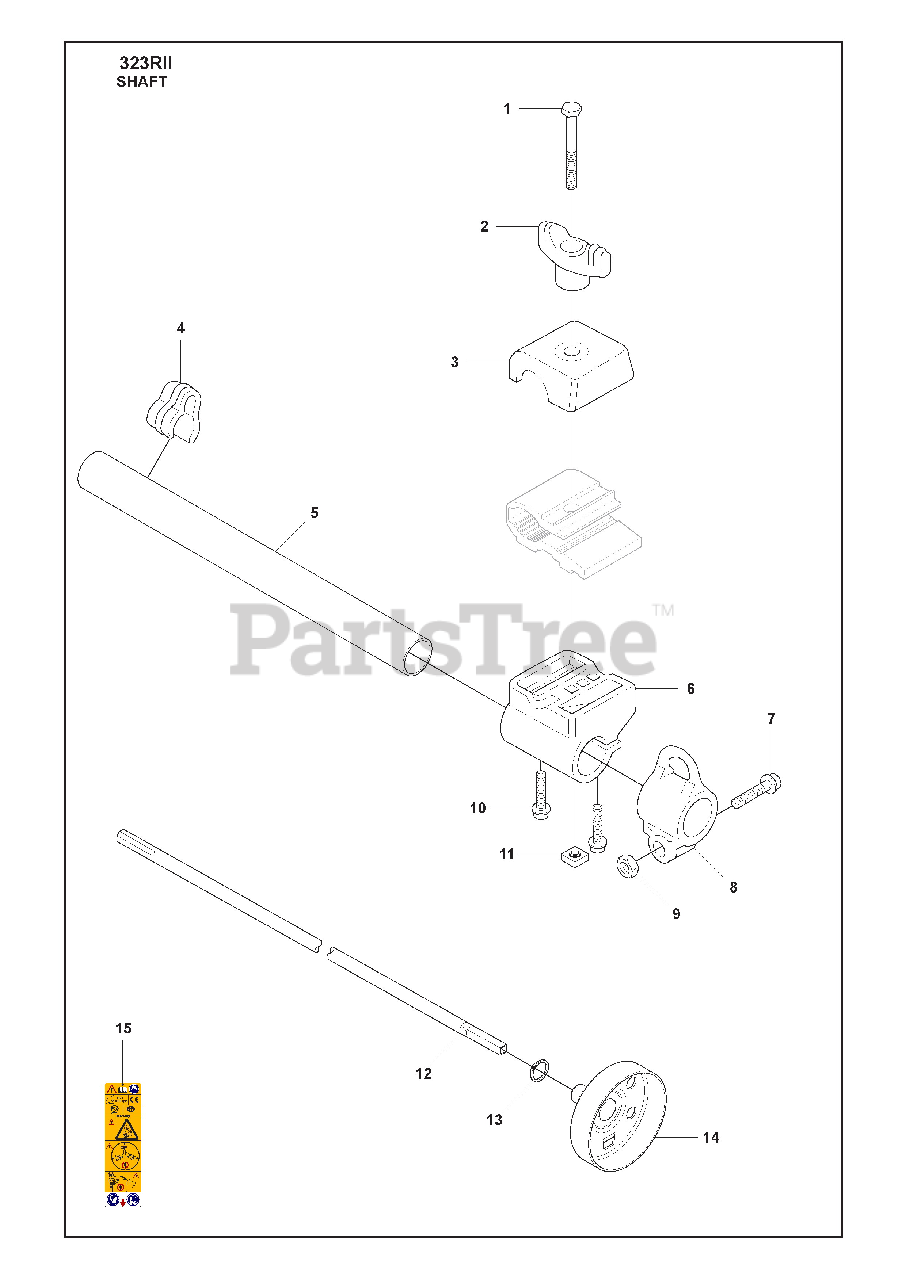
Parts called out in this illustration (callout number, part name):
5	DRIVE TUBE ASSEMBLY
7	SCREW
8	HARNESS HOLDER
12	DRIVE SHAFT
13	RETAINING RING SGA 10
14	CLUTCH DRUM
15	RP WARNING DECAL
